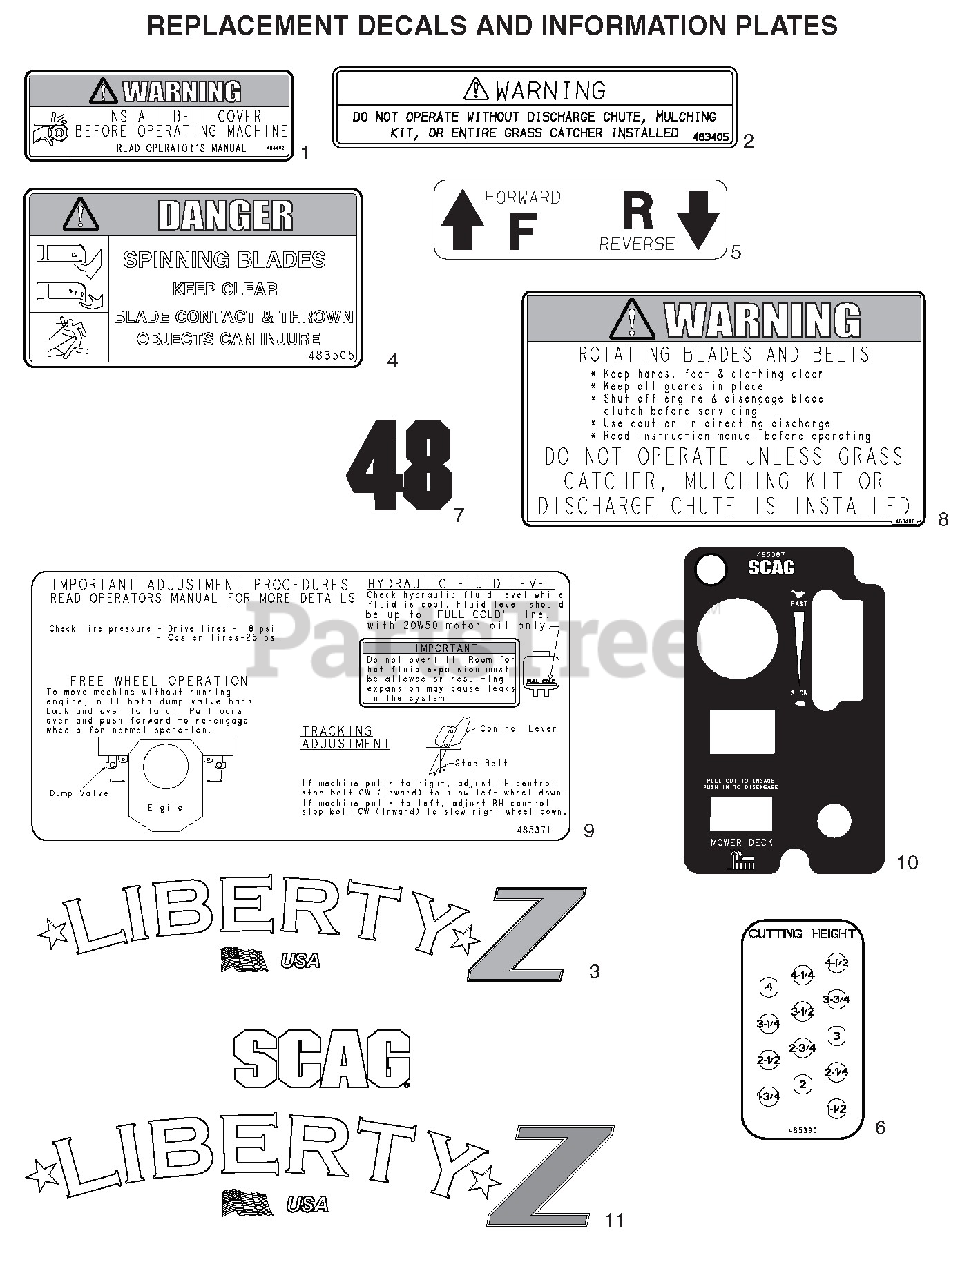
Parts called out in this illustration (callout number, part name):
1	Decal, Belt Cover
2	Decal, Warning
3	Decal, Liberty Z - Bumper
4	Decal, Spinning Blades
5	Decal, Traction Control
6	Decal, Height of Cut
7	Decal, 48
7	Decal, 52
8	Decal, Knives
9	Decal, Adjustments - SZL
10	Decal, Instrument Panel - SZL
11	Decal, Liberty Z
